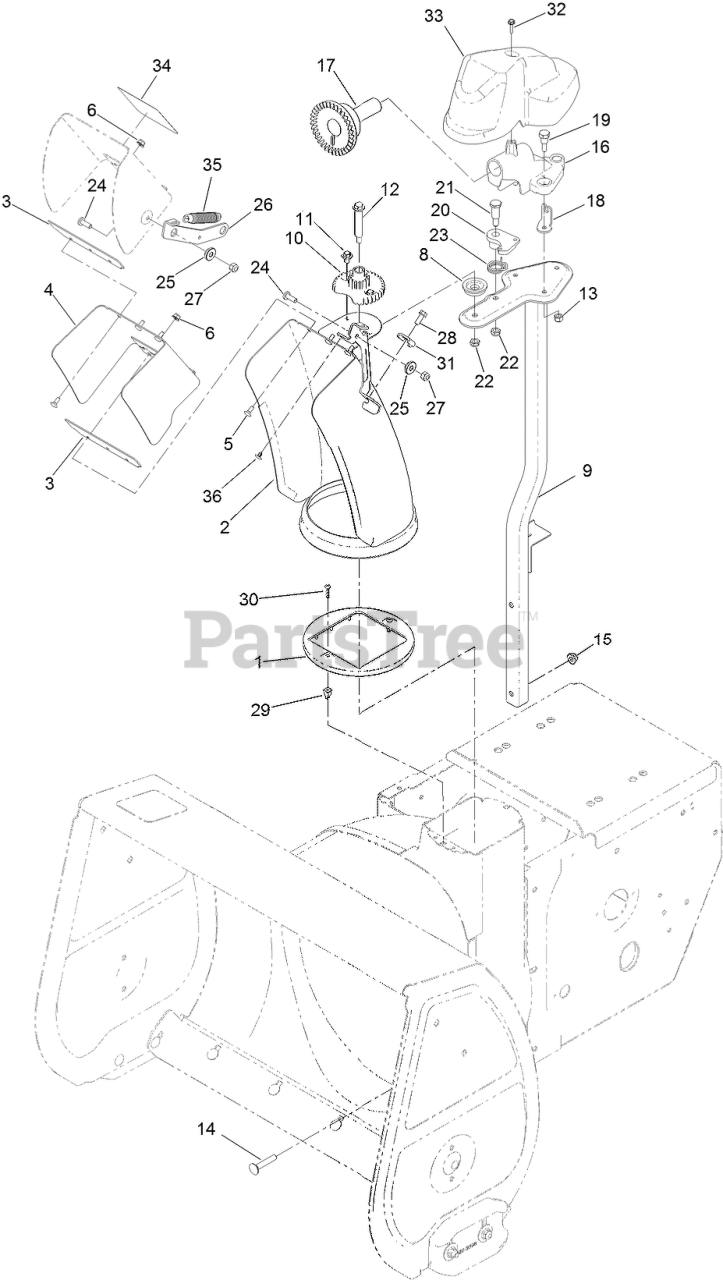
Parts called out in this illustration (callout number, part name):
1	GUIDE-CHUTE
2	LOWER CHUTE ASM
3	GASKET-DEFLECTOR
4	MIDDLE DEFLECTOR ASM
5	BOLT-CARR
6	NUT-HF
8	SPACER-CHUTE
9	CHUTE POST ASM
10	GEAR-CHUTE
11	SCREW AND WASHER ASM
12	BOLT-SHOULDER
13	NUT-HEX
14	BOLT-CAR
15	NUT-HF
16	MOUNT-GEAR, FACE
17	GEAR-FACE
18	ANCHOR-CABLE
19	SCREW-SHOULDER
20	LATCH-CHUTE
21	SCREW-SHOULDER, HH
22	NUT-HEX
23	SPRING-TORSION
24	SCREW-PH
25	BUSHING-PIVOT
26	LINK-DEFLECTOR
27	NUT-HEX
28	SCREW-HWH
29	GROMMET-SCREW
30	SCREW-PPH
31	CLAMP-CABLE
32	SCREW-PLASTITE, HWH
33	COVER-GEAR, FACE
34	DECAL-DANGER
35	SPRING-EXTENSION
36	PLUG-PLASTIC
